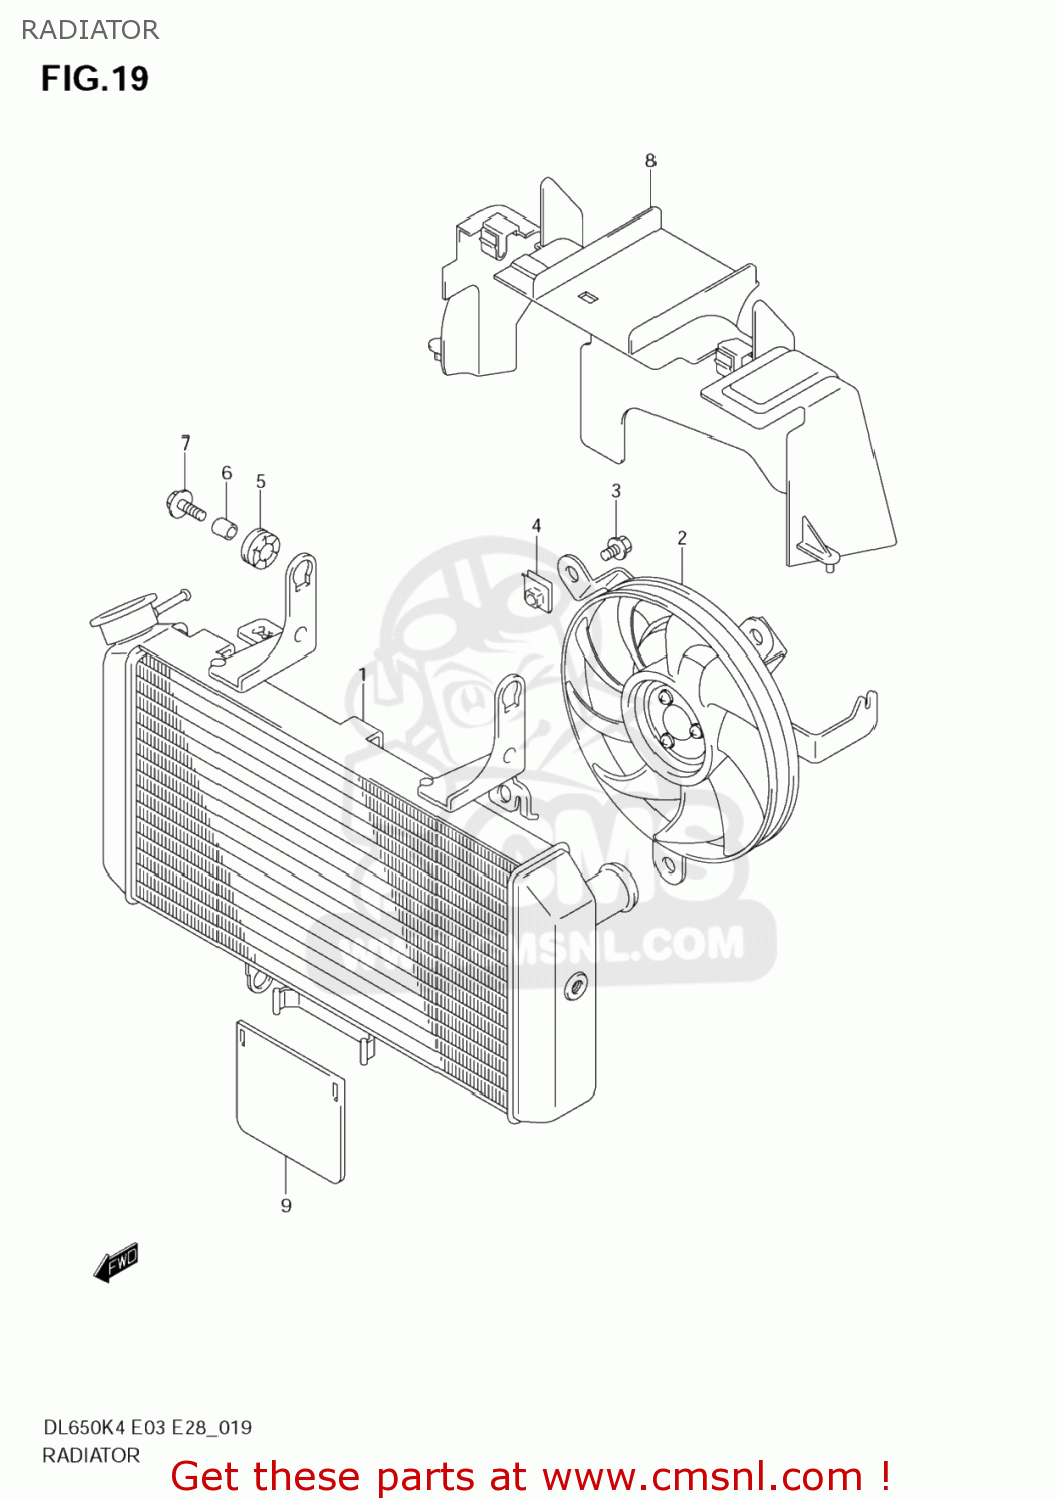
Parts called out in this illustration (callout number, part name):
1	RADIATOR ASSY,WATER
2	FAN ASSY,RADIATOR
3	BOLT
4	NUT
5	CUSHION
6	SPACER(6.5X10X12)
7	BOLT(6X25)
8	SHIELD,RADIATOR HEAT
9	RUBBER,RADIATOR UNDER
